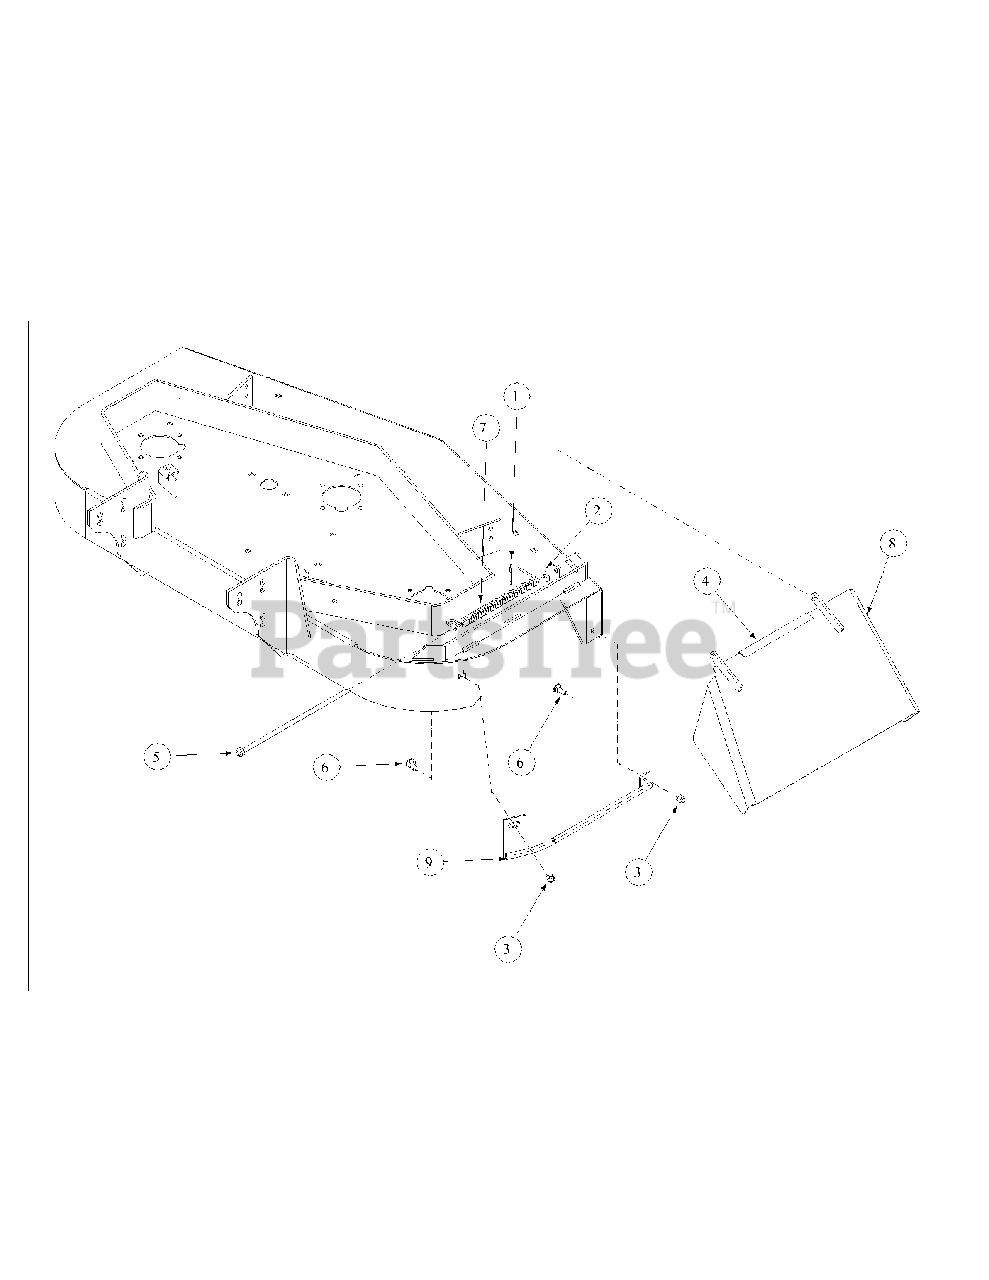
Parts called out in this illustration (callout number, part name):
1	Cotter Pin, 5/32 x 1" Lg. Zinc
2	Flat Washer, 3/8 Zinc
3	Lock Nut, Nylon Insert, 3/8-16
4	Decal, Cut LIne
5	Pin Deflector Assembly, Weldment
6	Carriage Bolt, 3/8-16 x 2
7	Torsion Spring
8	Chute Assembly
9	Stiffner Assembly, 48
